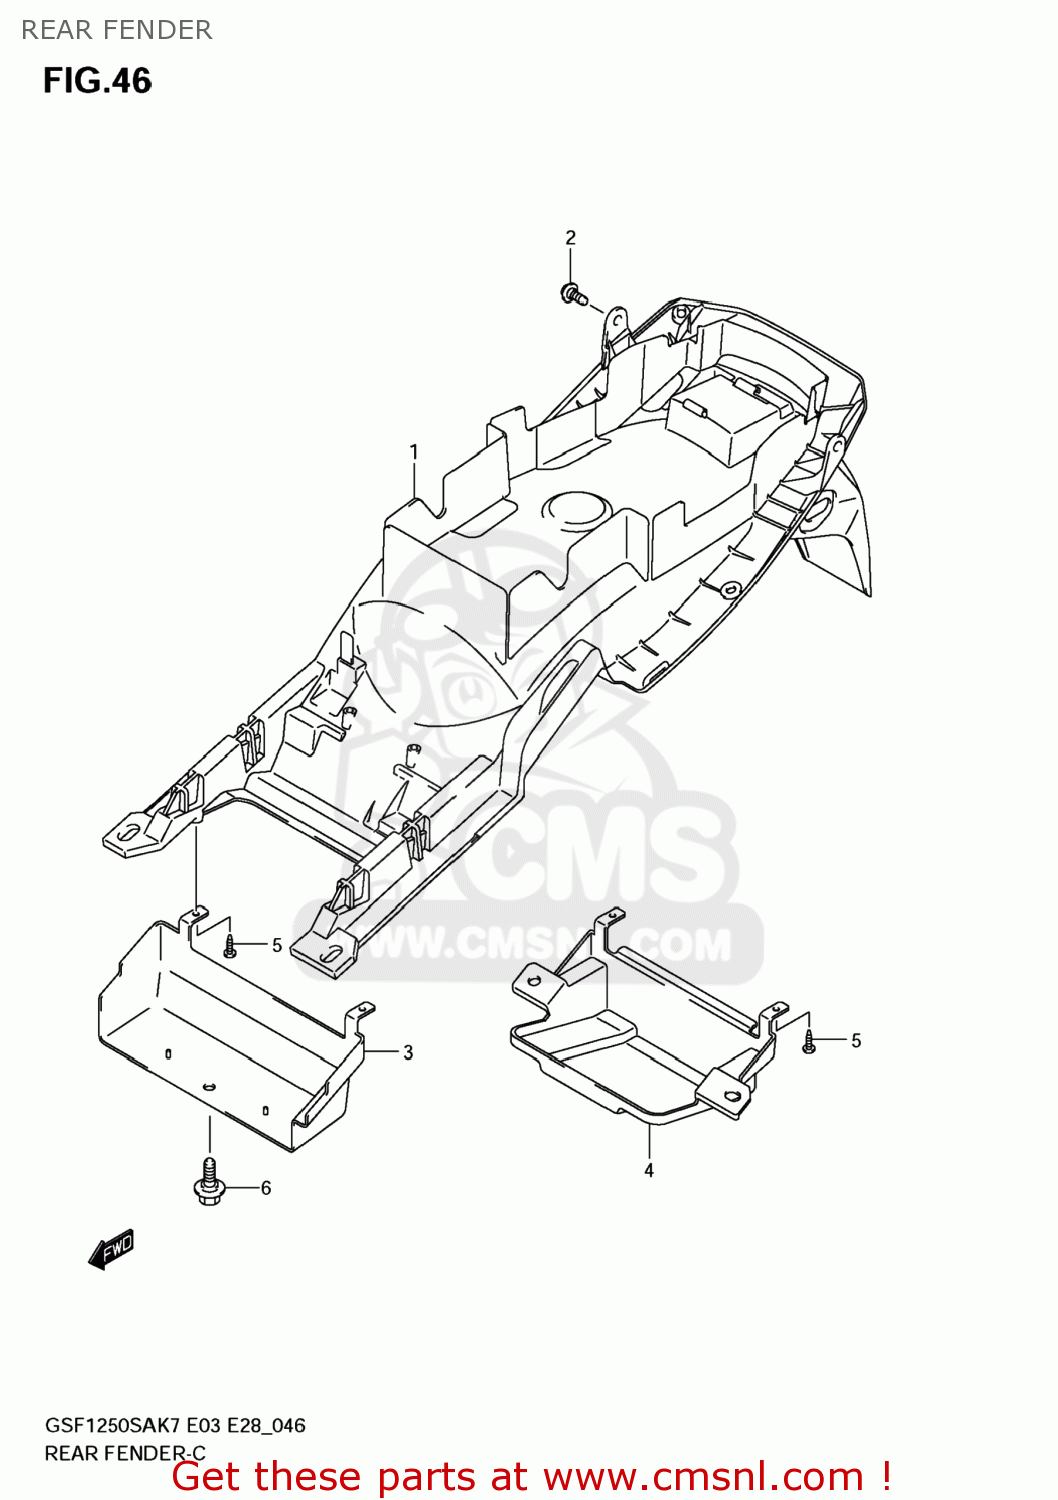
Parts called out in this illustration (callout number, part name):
1	FENDER,RR
2	BOLT
3	COVER,HYDR ABS UNIT
4	COVER
5	SCREW
6	BOLT(6X17.8)
